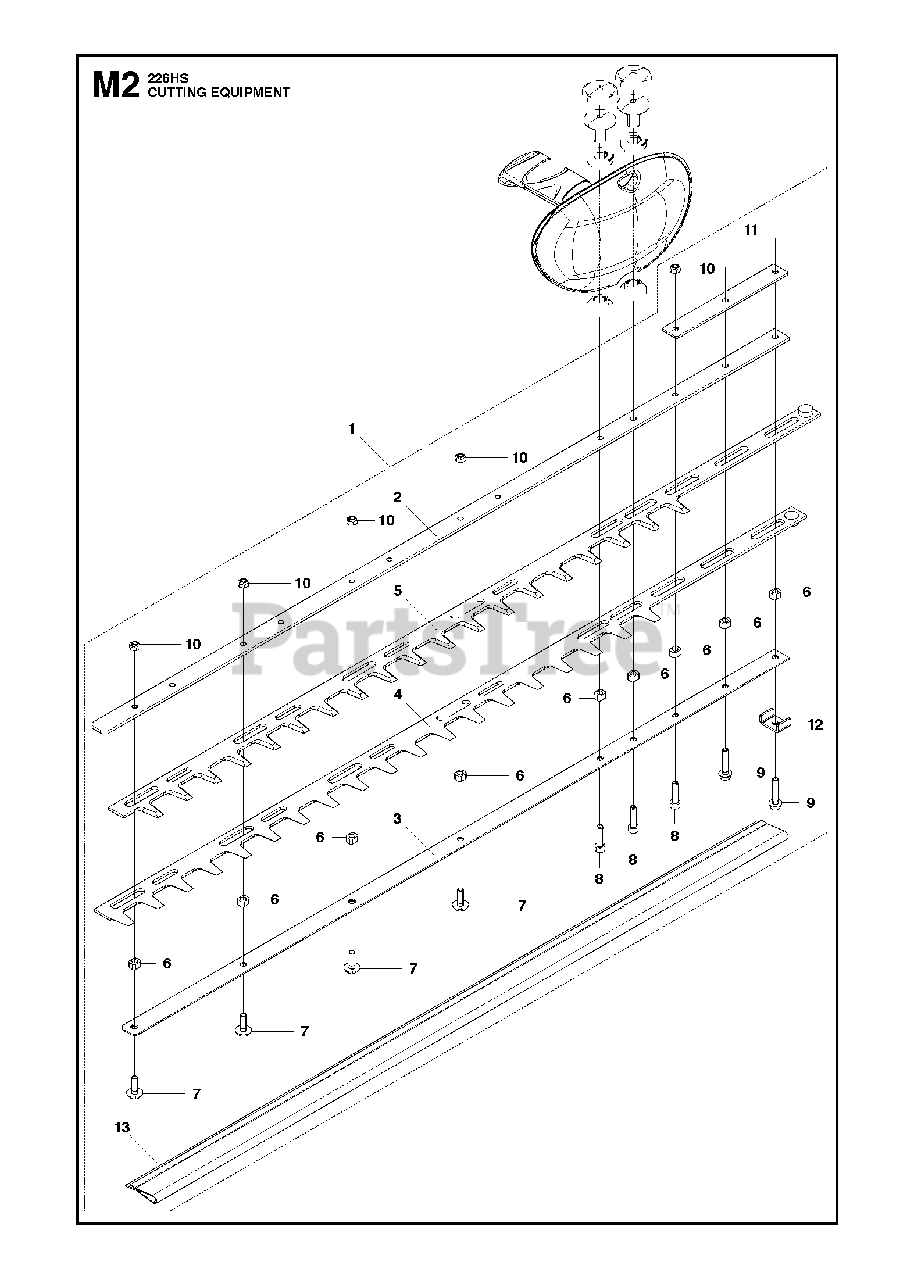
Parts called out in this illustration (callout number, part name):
1	BLADE ASSY
2	Plate, Upper
3	PLATE LOWER
4	BLADE LOWER
5	BLADE UPPER
6	SPACER
7	SCREW
8	BOLT
9	BOLT
10	NUT
11	PLATE
12	BRACKET
13	Cover
